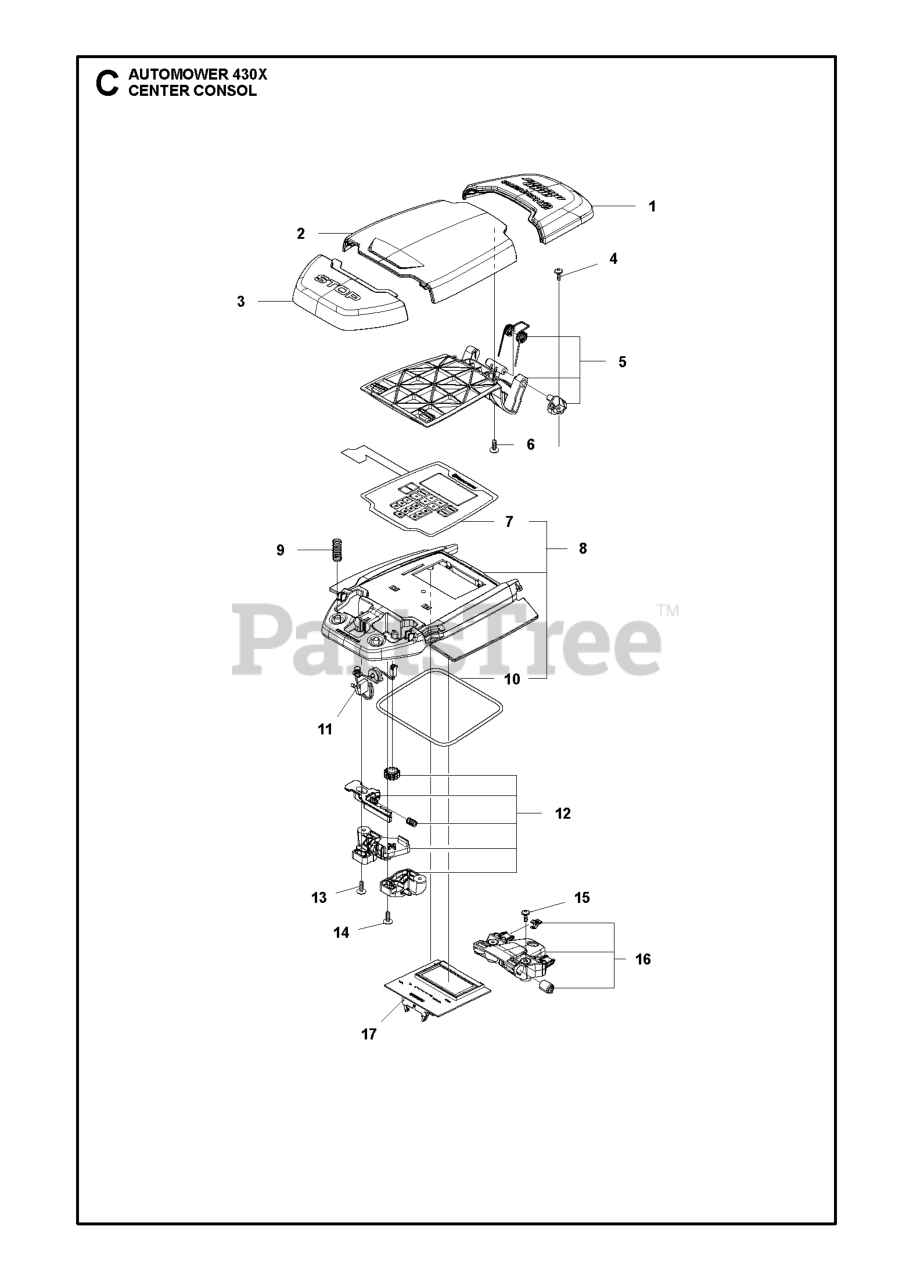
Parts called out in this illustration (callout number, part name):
1	COVER FRONT 430X GREY
2	HATCH BLACK NCS S 9000-N
3	BUTTON STOP
4	SCREW 14MM
5	HINGE KIT KIT
6	SCREW 14MM
7	KEYBOARD 330X
8	COVER KIT DISPLAY 430XH,450XH
8	COVER KIT DISPLAY ILLUMINATED
9	SPRING
10	SEALING STRIP
11	SWITCH STOP BUTTON NO ANCHOR
12	LOCK KIT
13	SCREW 14MM
14	SCREW 14MM
15	SCREW 14MM
16	SUPPORT KIT FRONT
17	PRINTED CIRCUIT ASSY HMI BOARD
17	PRINTED CIRCUIT ASSY PCBA MMI
